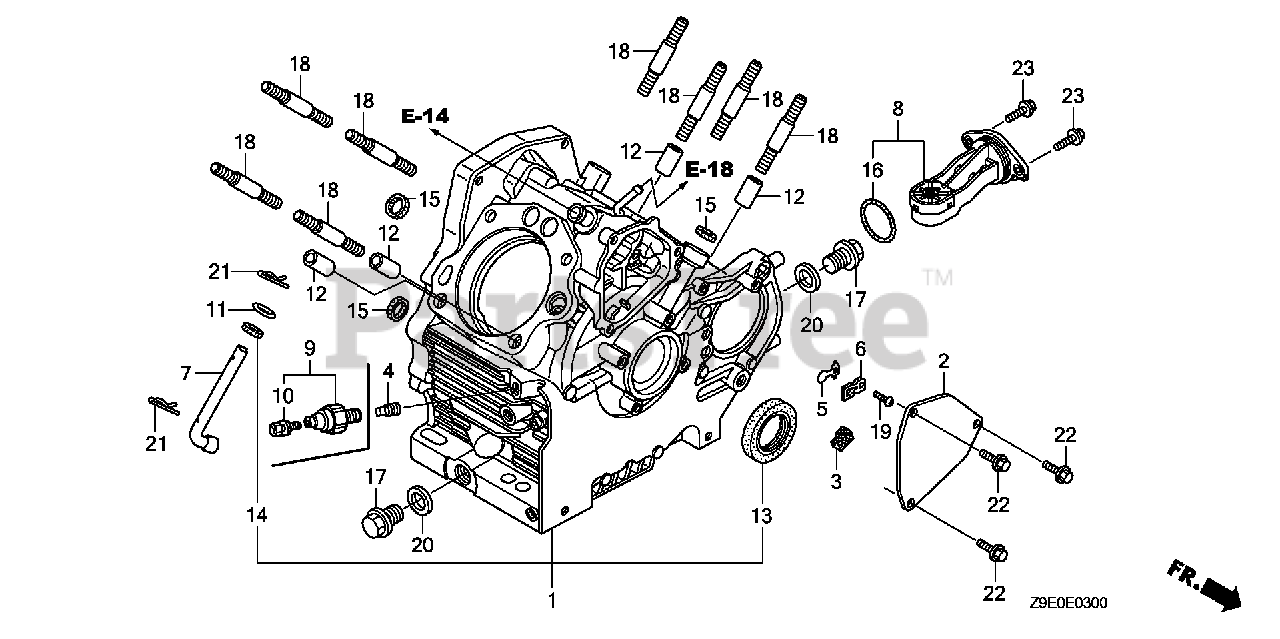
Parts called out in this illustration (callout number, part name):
1	CRANKCASE ASSY.
2	COVER, BREATHER
3	FILTER, BREATHER
4	BOLT, SEALING
5	VALVE, OIL OUTLET
6	PLATE, STOPPER
7	SHAFT, GOVERNOR ARM
8	SWITCH ASSY., OIL LEVEL
11	WASHER, PLAIN (10MM)
12	PIN, DOWEL (12X20)
13	OIL SEAL (38X58X9)
14	OIL SEAL (10X16X5)
15	GASKET, OIL PASSAGE
16	O-RING (37.9X2.4)
17	BOLT, DRAIN PLUG (20MM)
18	BOLT, STUD (10X40)
19	SCREW, PAN (3X8)
20	WASHER, DRAIN PLUG (20MM)
21	PIN, LOCK (10MM)
22	BOLT, FLANGE (6X14)
23	BOLT, FLANGE (6X16)
